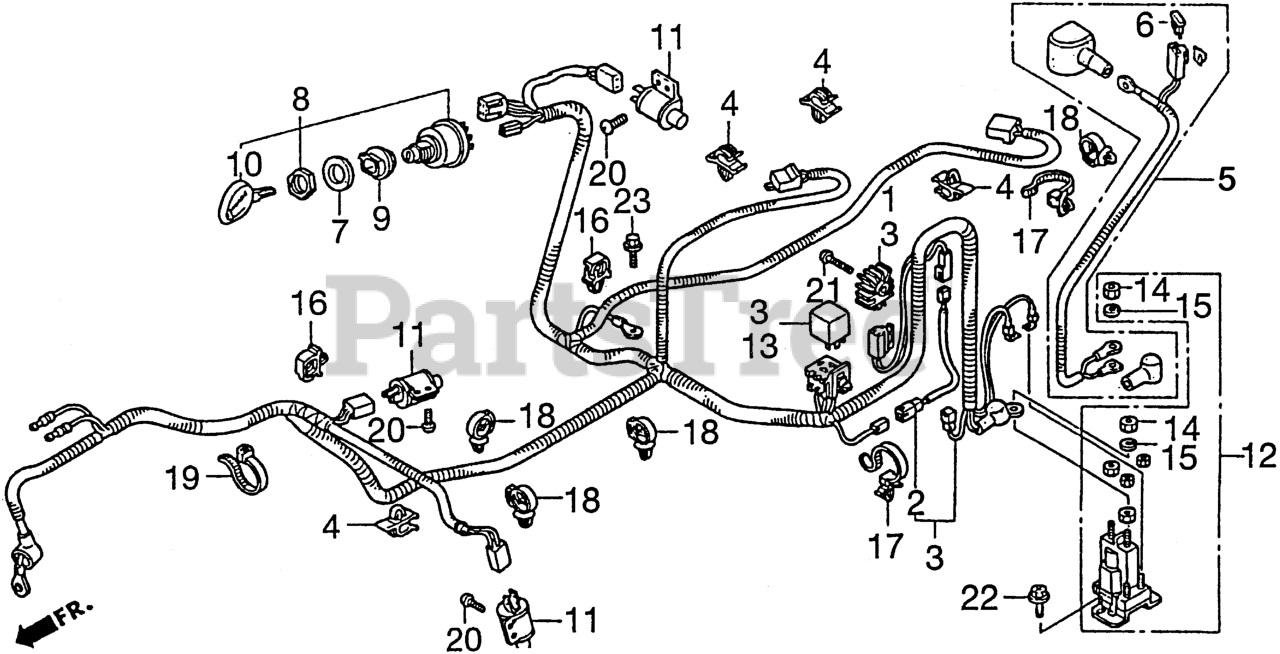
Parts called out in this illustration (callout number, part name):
1	RECTIFIER, REGULATOR (5A)
3	WIRE HARNESS ASSY., MAIN
4	CLIP, WIRE HARNESS
5	CABLE ASSY., BATTERY
6	FUSE, BLADE (5A)
7	COLLAR, FR. TURN SIGNAL
8	SWITCH ASSY., COMBINATION
9	BASE, COMBINATION SWITCH
10	KEY, COMBINATION SWITCH
11	SWITCH ASSY., P.T.O. CLUTCH
12	SWITCH ASSY., STARTER MAGNETIC
13	RELAY ASSY. (40A)
15	WASHER, SPRING (N/A: SEE ASSEMBLY)
16	CLIP, HARNESS (15MM) (BLUE)
17	STRAP, CABLE (105MM) *NH1* (Honda Code 1685536). (BLACK)
18	CLIP, WIRE HARNESS
19	BAND, WIRE
20	SCREW, TAPPING (5X8) (NOT AVAILABLE)
21	SCREW, TAPPING (6X30)
22	SCREW, TAPPING (6X12)
23	BOLT, FLANGE (8X12)
